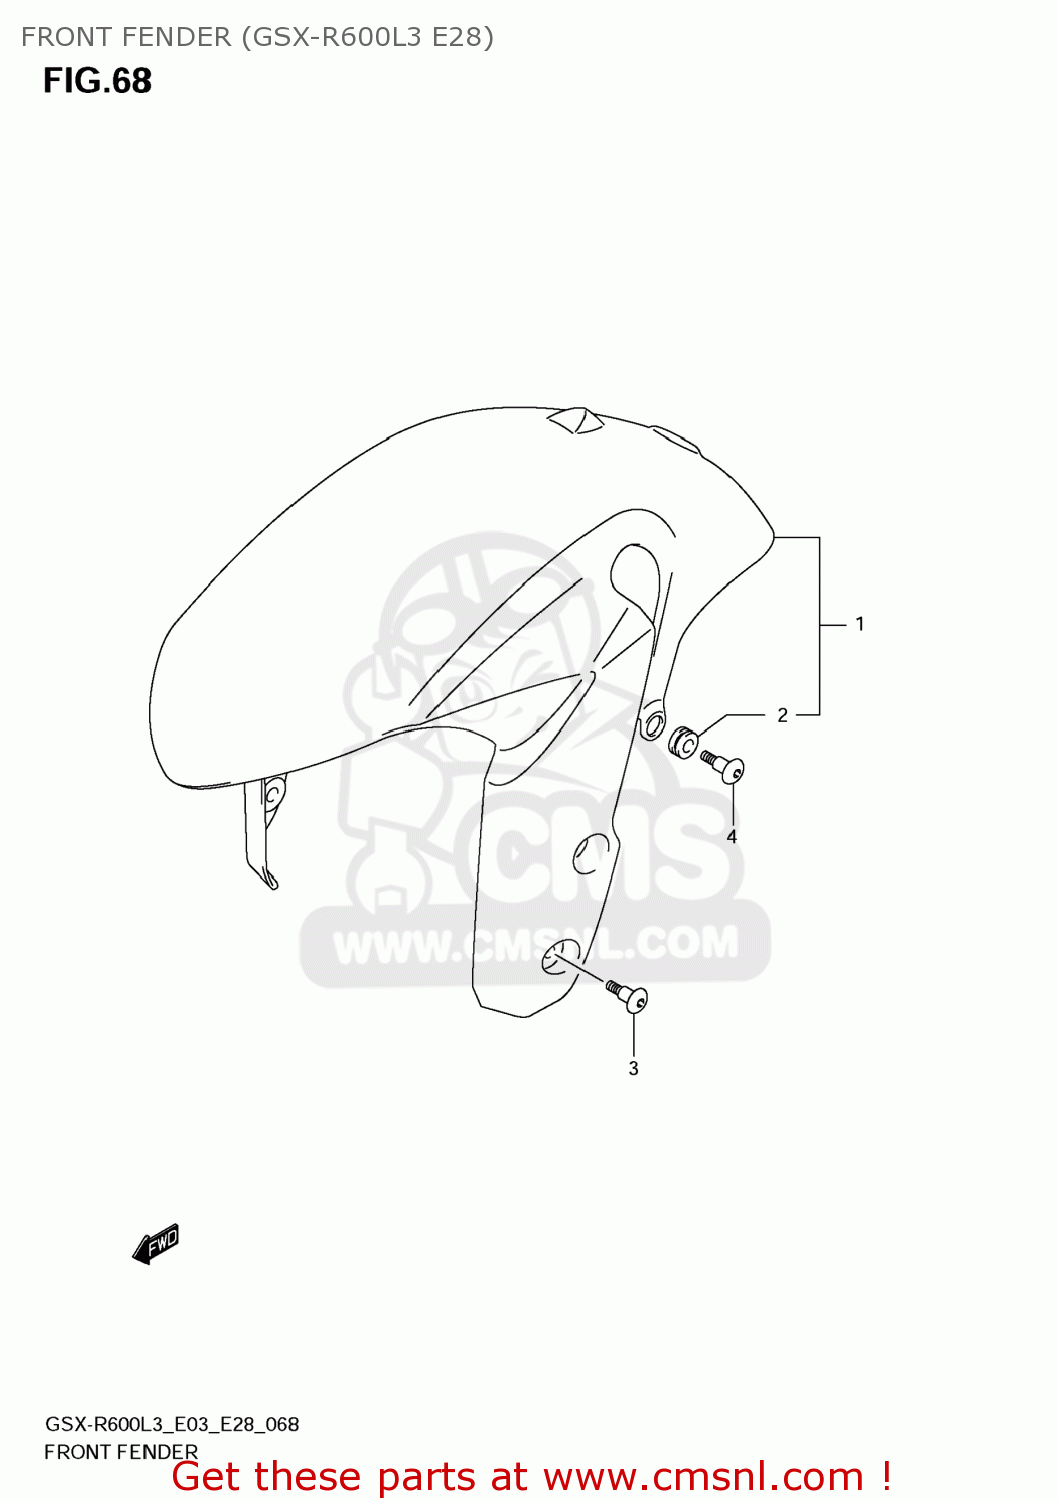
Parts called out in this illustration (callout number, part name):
1	FENDER ASSY,FR(BLUE)
2	CUSHION
3	SCREW(6X16)
4	SCREW(6X16)
